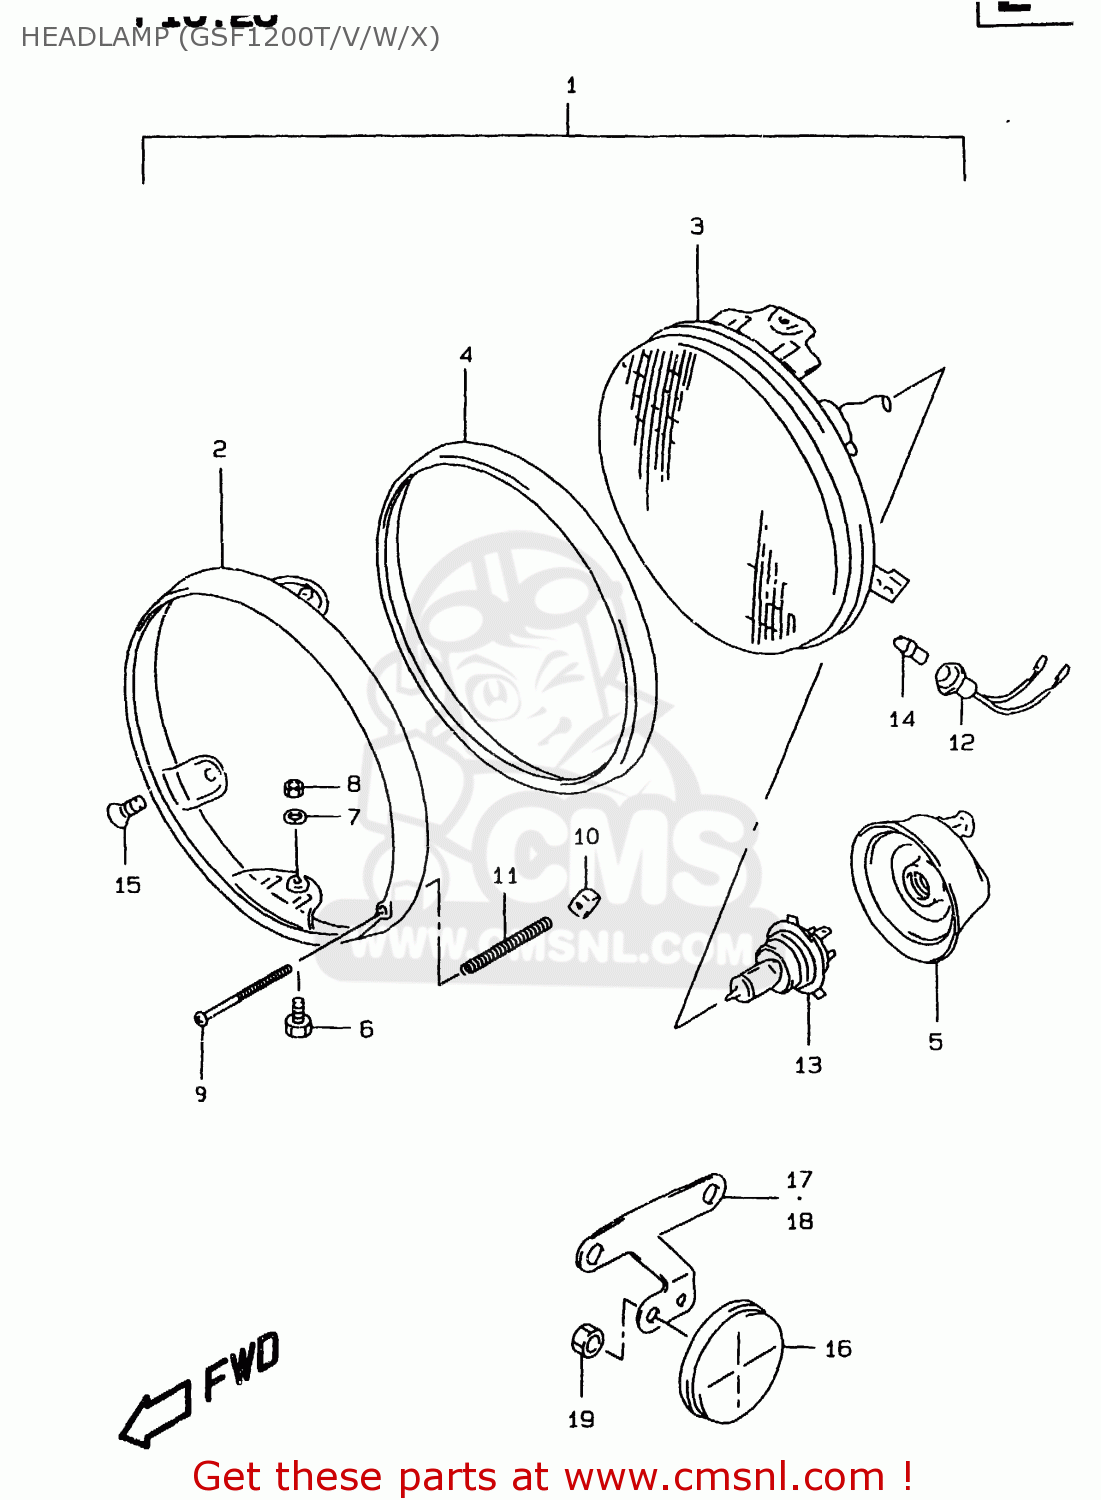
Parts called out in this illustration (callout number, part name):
1	HEADLAMP ASSY
2	RIM,HEADLAMP
3	LAMP UNIT
4	RING
5	COVER,SOCKET
6	H/LAMP LENS UNIT FITING SCRE
7	WASHER,LOCK
8	NUT
9	SCREW
10	NUT
11	SPRING,ADJUSTING
12	SOCKET,PARKING LAMP
13	BULB(12V60/55W,H4)
14	BULB(12V4W)
15	SCREW
16	REFLECTOR,REFLEX FR
17	BRACKET,FR SIDE REFLECTOR,R
18	BRACKET,FR SIDE REFLECTOR,L
19	NUT
